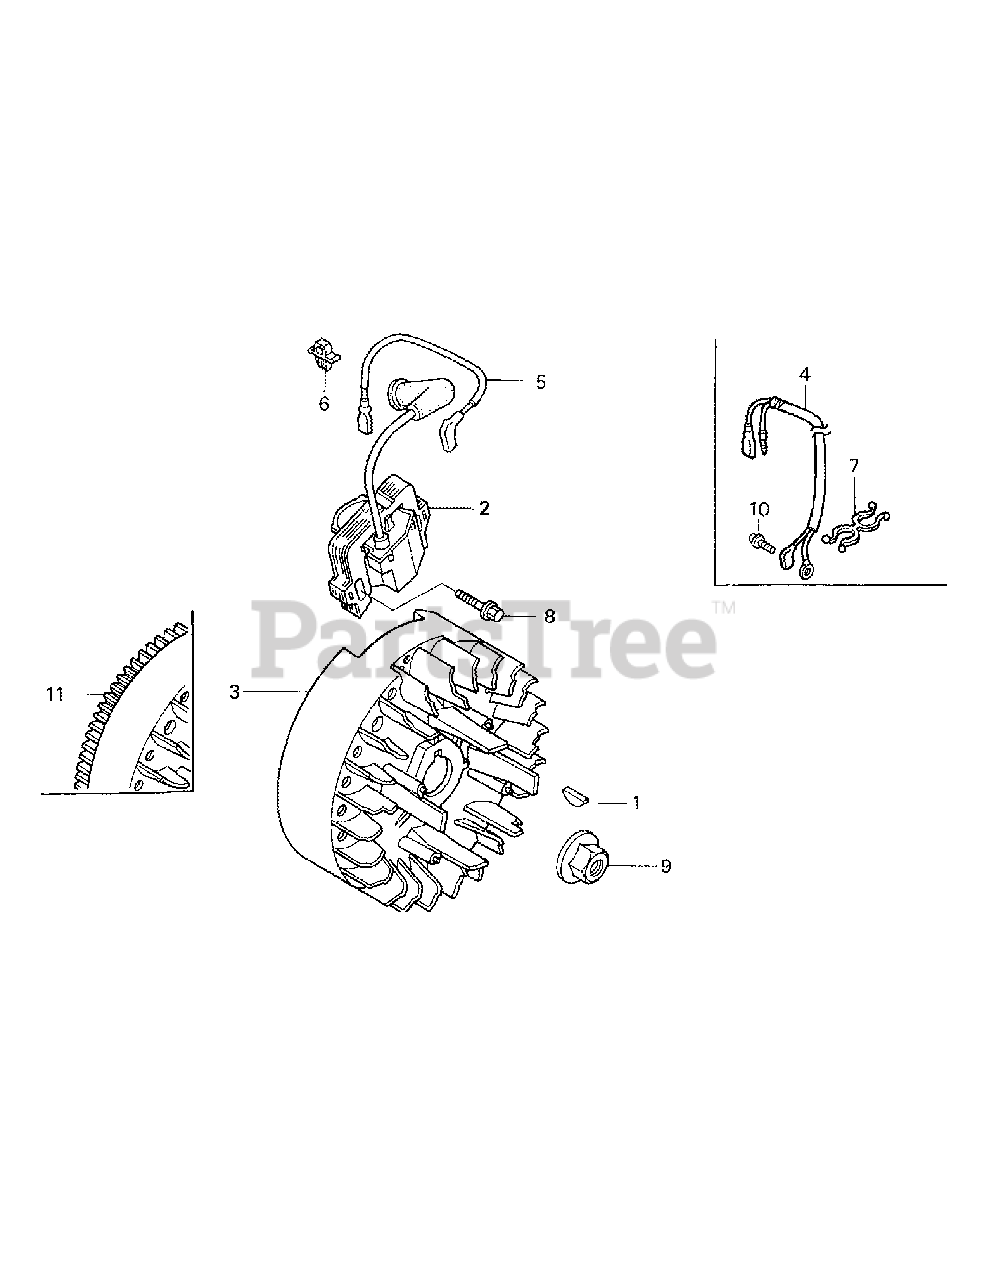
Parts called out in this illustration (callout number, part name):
1	Special Woodruff Key, 25 x 18
2	Ignition Coil Assembly
5	Stop Switch Wire
6	Stop Switch Wire Holder
8	Flange Bolt, 6 x 20
9	Flange Nut, 14mm
